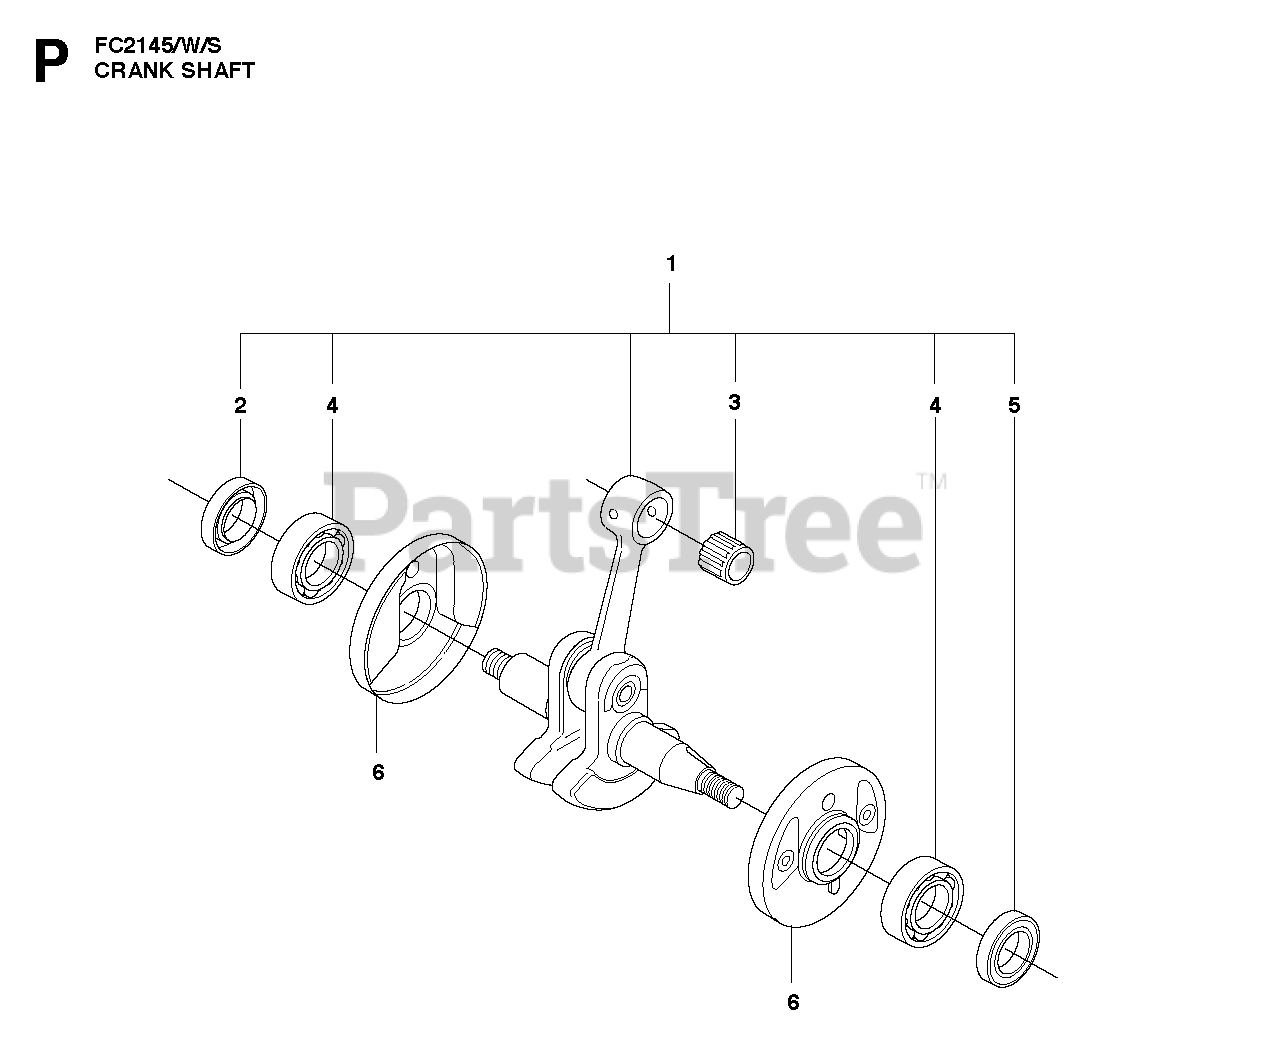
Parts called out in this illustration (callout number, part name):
1	CRANKSHAFT
2	SEALING RING
3	RP SUPPORT BUSHING
4	BALL BEARING-6202-C3 SKF
5	SEAL RING
6	COLLAR
